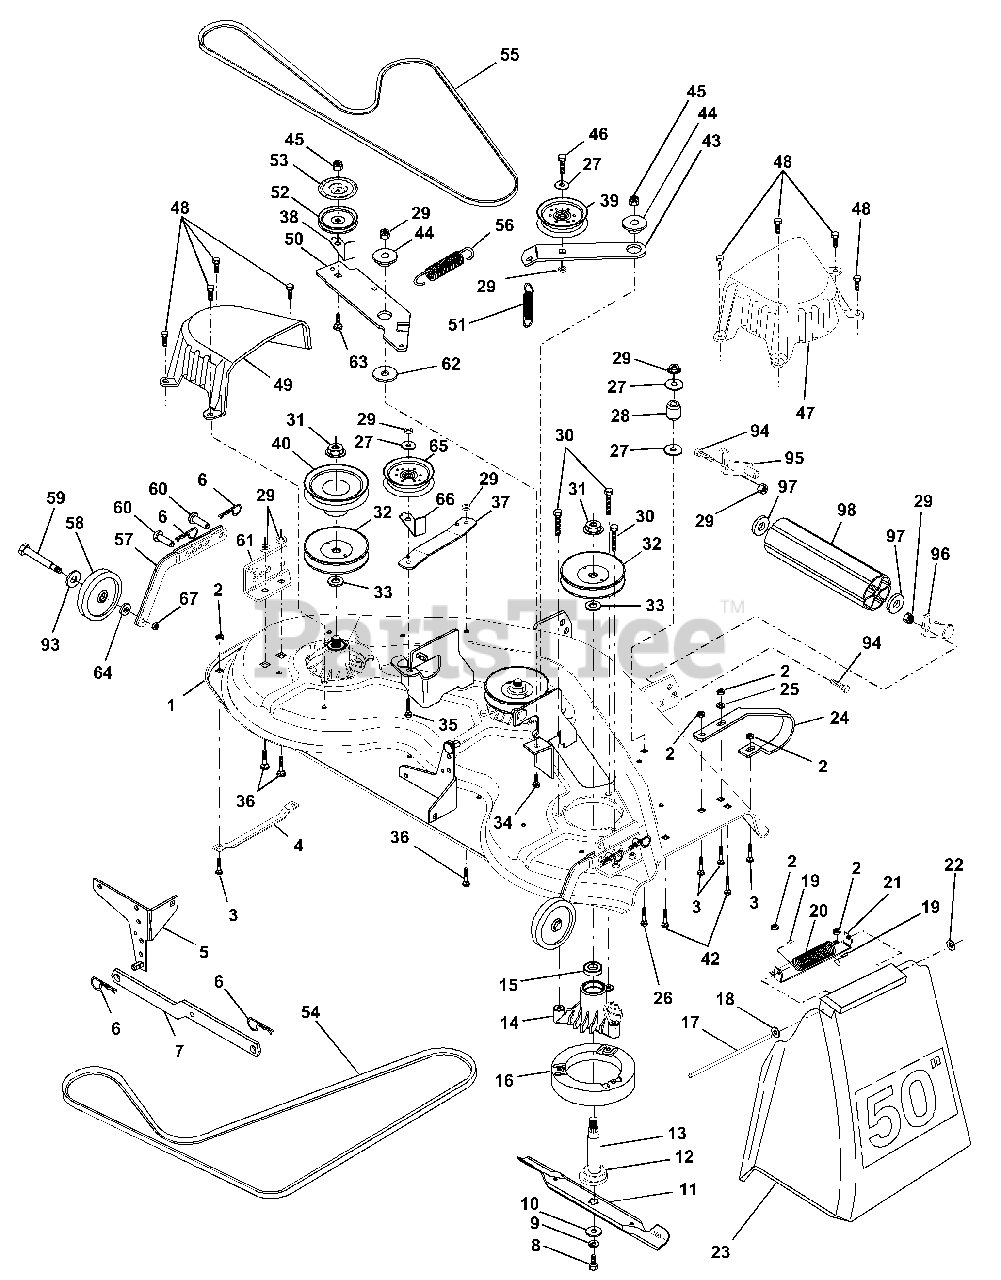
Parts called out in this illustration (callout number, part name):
1	Deck Asm., Mower 50" Vented
2	Locknut, Hex W/Ins 5/16-18 Unc
3	Bolt, Carriage 5/16-18 x 3/4
4	Runner, Mower LH
5	Bracket Asm., Sway Bar
6	Retainer, Spring
7	Arm Suspension, Rear
8	Bolt 3/8-24 x 1.25 Gr. 8 Patched
9	Washer, Lock Hvy 3/8 Unplated
10	Washer, Hard Blade Mower Vented
11	Blade (3 Required)
12	Bearing, Ball #6204
13	Shaft Asm., W/Lower Brg
14	Housing, Mandrel 50" Vent
15	Bearing, Ball Mandrel
16	Stripper, Mower Vented
17	Rod, Hinge
18	Washer 11/32 x 5/8 x 16 Ga.
19	Cap, Sleeve
20	Spring, Torsion Deflector
21	Bracket, Deflector
23	Shield, Deflector Mower
24	Runner, RH
25	Washer 11/32 x 3/4 x 16 Ga.
26	Bolt, Carriage 3/8-16 x 1-3/4 Gr. 5
27	Washer 13/32 x 13/16 x 16 Ga.
28	Spacer, Spring Stop Idler
29	Nut, Lock Hex W/Wsh 3/8-16 Unc
30	Screw Thdrol Hex Head
31	Nut, Flg Top Lock Cntr 9/16
32	Pulley, Mandrel
33	Washer, Spacer Mower Vented
34	Bolt, Carriage 3/8-16 x 1-1/4
35	Bolt, Carriage 3/8-16 x 2
36	Bolt, Carriage 3/8-16 x 1 Gr. 5
37	Stiffener, Arm Idler
38	Keeper, Belt Idler
39	Pulley, Idler Flat
40	Pulley, Driven
42	Bolt, Carriage 5/16-18 Unc x 3/4
43	Arm, Idler Secondary
44	Spacer, Retainer
45	Nut, Crownlock 3/8-16 Unc
46	Bolt, Fin Hex 3/8-16 Unc x 1-3/4
47	Cover, Mandrel RH
48	Screw, Thd Roll 1/4-20 x 5/8
49	Cover, Mandrel LH
50	Arm, Idler Primary
51	Spring, Secondary
52	Pulley, Idler V Groove
53	Shield, Idler
54	V-Belt, Mower Primary
55	V-Belt, Mower Secondary
56	Spring, Primary
57	Bar Asm., Wheel Gauge
58	Wheel, Gauge
59	Bolt, Shoulder
60	Pin, Clevis
61	Bracket, Wheel Gauge
62	Washer Hardened
63	Bolt Carriage 3/8-16 x 1-1/2
64	Washer 3/8 x 7/8 x 14 Ga.
65	Pulley Idler Flat Mower
66	Keeper, Belt Idler 50" Vent
67	Nut, Center Lock 3/8-16
95	Bracket, Asm. Noseroller LH
96	Bracket, Asm. Noseroller RH
97	Washer 17/32 x 7/8 x 16 Ga.
98	Roller, Nose
99	Bolt, Fin Hex 3/8-16 x 1
100	Washer 17/32 x 15/16 x 12 Ga.
